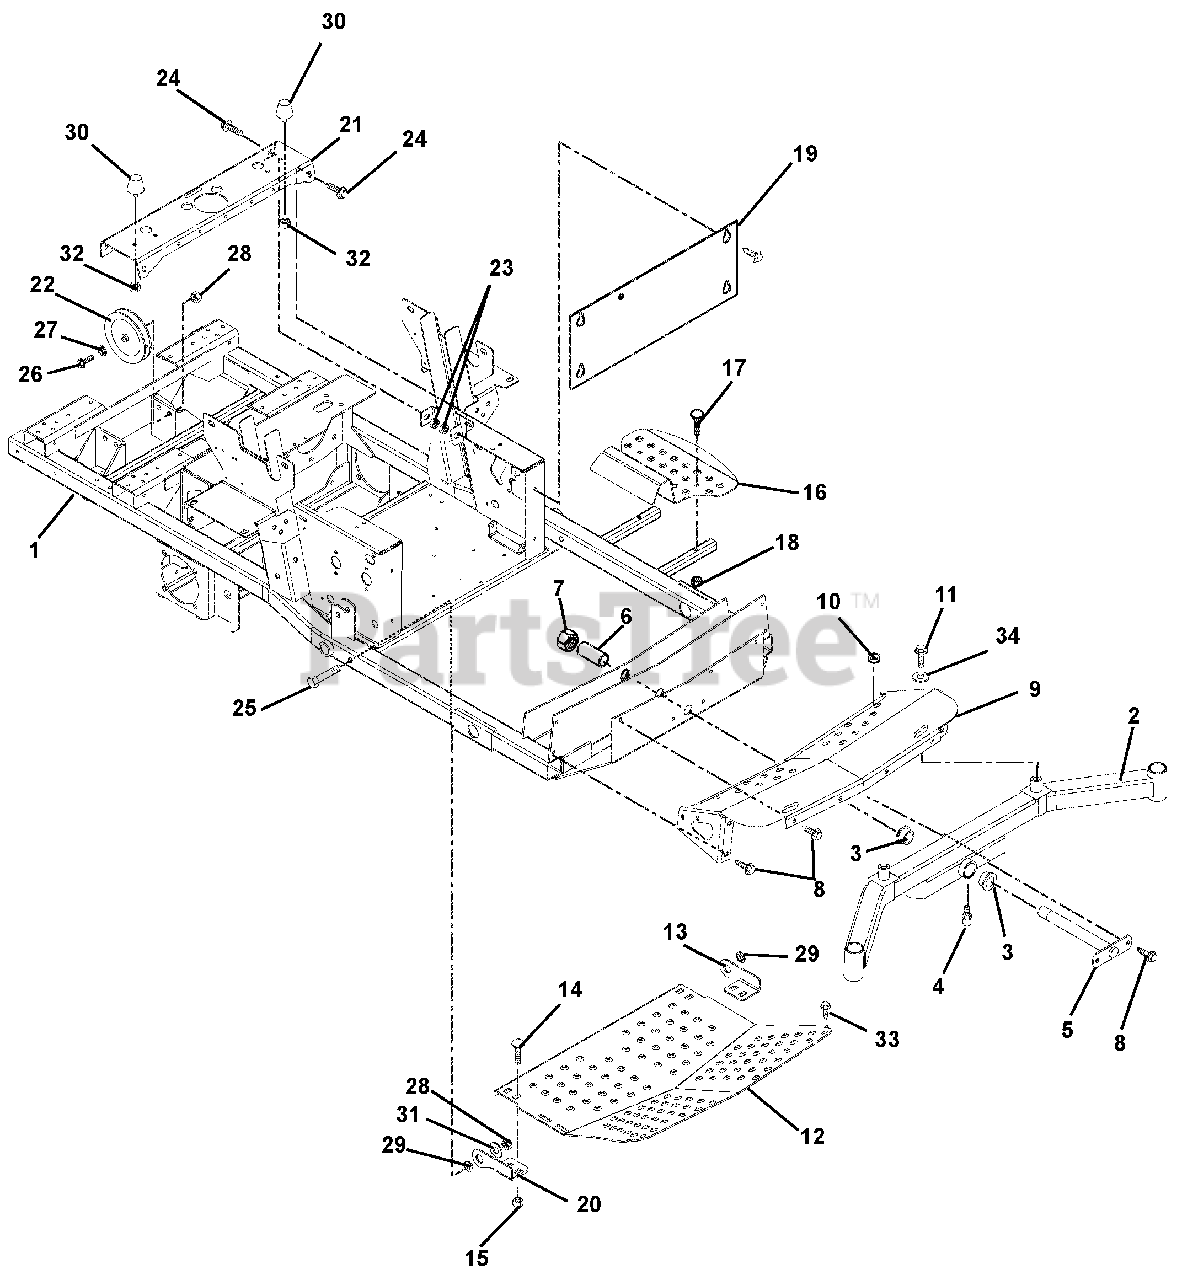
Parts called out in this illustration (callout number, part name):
1	Weldment, Frame
2	Weldment, Front Axle
3	Bushing, Flange 1.020 x 1.385 x .75 x 1.75
4	Fitting, Lube .25-28 x .256
5	Pin, Axle
7	Nut, Locking Nylon 1.0-14
8	Screw, Tapping .38-16 x .75
9	Weldment, Axle Cover
10	Button, Bumper
11	Bolt, Hex .50-20 x 1.00 Grade 5
12	Panel, Inspection
13	Hinge, Footboard Left Hand
14	Bolt, Round Head Square Neck .38-16 x 1.00 Grade 5
15	Nut, Locking Top Flange .38-16
16	Step, Ingress
17	Bolt, Round Head Square Neck .31-18 x 1.75 Grade 5
18	Nut, Locking Top Flange .31-18
19	Plate, Kick
20	Hinge, Footboard Right Hand
21	Channel, Cross
22	Pulley, Idler
23	Nut, Retainer .375-16 x .37
24	Bolt, Serrated Flange Washer Head .38-16 x 1.00
25	Bolt, Hex .50-13 x 3.25 Grade 5
26	Bolt, Hex .50-13 x 2.25 Grade 5
27	Washer, Flat Steel .505 x .88 x .072
28	Nut, Locking Top Flange .50-13
29	Bushing, Flange .515 x .75 x .275 x 1.12
31	Washer, Flat Steel .563 x 1.38 x .109
32	Nut, Locking Flange .312-24
33	Screw, Tapping Hex Washer Head .38-16 x 1.00
34	Washer, Flat Steel .518 x 2.00 x .105
